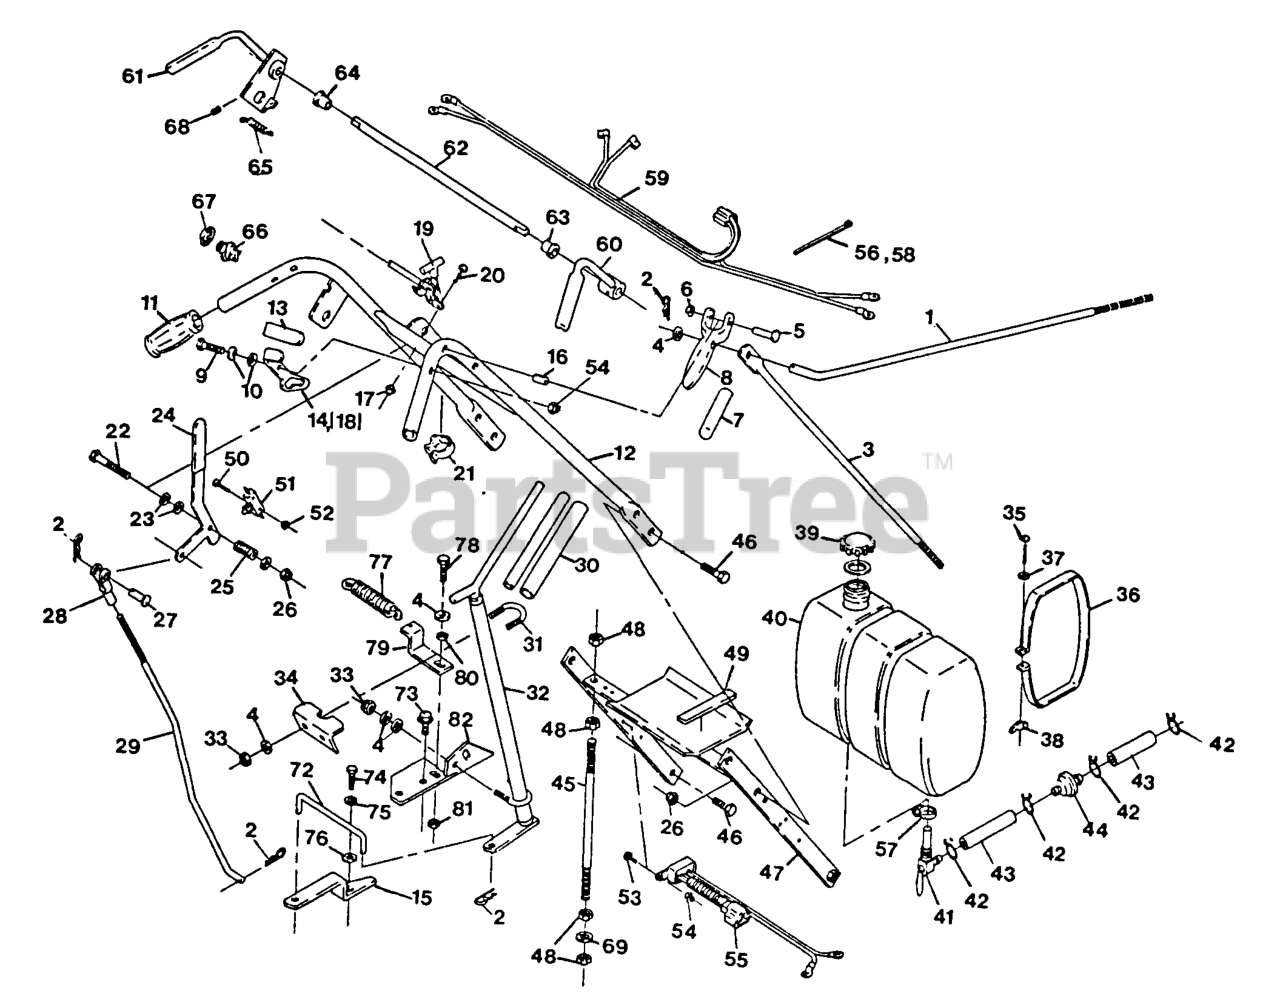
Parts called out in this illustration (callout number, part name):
1	LINKAGE,BRAKE
2	PIN-COTTER
3	LINKAGE,CALIPER
5	PIN-LEVER, DRIVE
6	NUT-PUSH
7	GRIP-LEVER, DRIVE
8	DRIVE LEVER ASM
10	WASHER-SPRING
13	GRIP-LATCH
14	LATCH,W/GRIP RH
15	LEVER,TRANSMISSION
16	PIN-ROLL
18	LATCH,W/GRIP LH
21	CLIP-CABLE
24	GRIP-LEVER
25	SPRING-COMPRESSION
27	PIN-CLEVIS
28	YOKE-ADJUSTABLE
29	LINKAGE,BLADE DRIVE
38	WINGNUT
39	CAP-FUEL
43	HOSE-FUEL
49	PAD,PLASTIC TANK
56	TIE-CABLE
57	CLAMP-HOSE
58	TIE-PLASTIC
62	ROD,CONNECTING
63	BUSHING-NYLON
64	BUSHING,FLANGED
65	SPRING-EXTENSION
66	SWITCH,OPERATOR CNTRL
75	WASHER-LOCK
